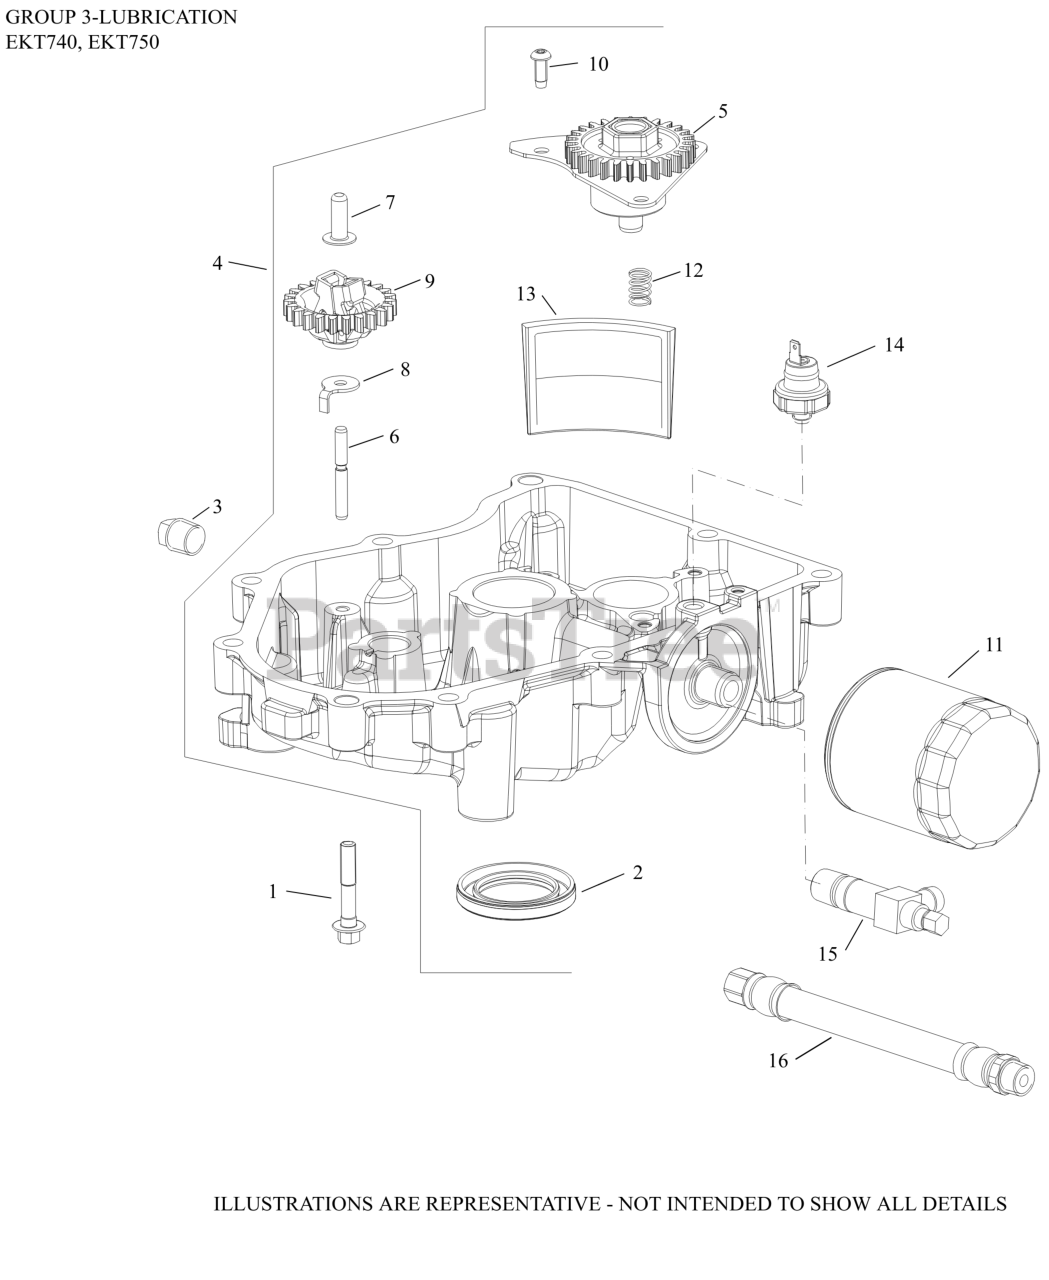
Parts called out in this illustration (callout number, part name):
1	SCREW, FLG M8X1.25X45
3	PLUG, SQ HD PIPE 3/8"
4	PAN ASSEMBLY, OIL-(#3219924S)
5	PUMP ASSEMBLY, OIL
6	SHAFT, GOVERNOR GEAR
7	PIN, GOVERNOR REGULATING
8	TAB, LOCKING
9	KIT, GOVERNOR GEAR
10	SCREW, BUTTON HEAD
11	OIL FILTER
12	SPRING, COMPRESSION
13	SCREEN, OIL
14	SENSOR, OIL PSI
